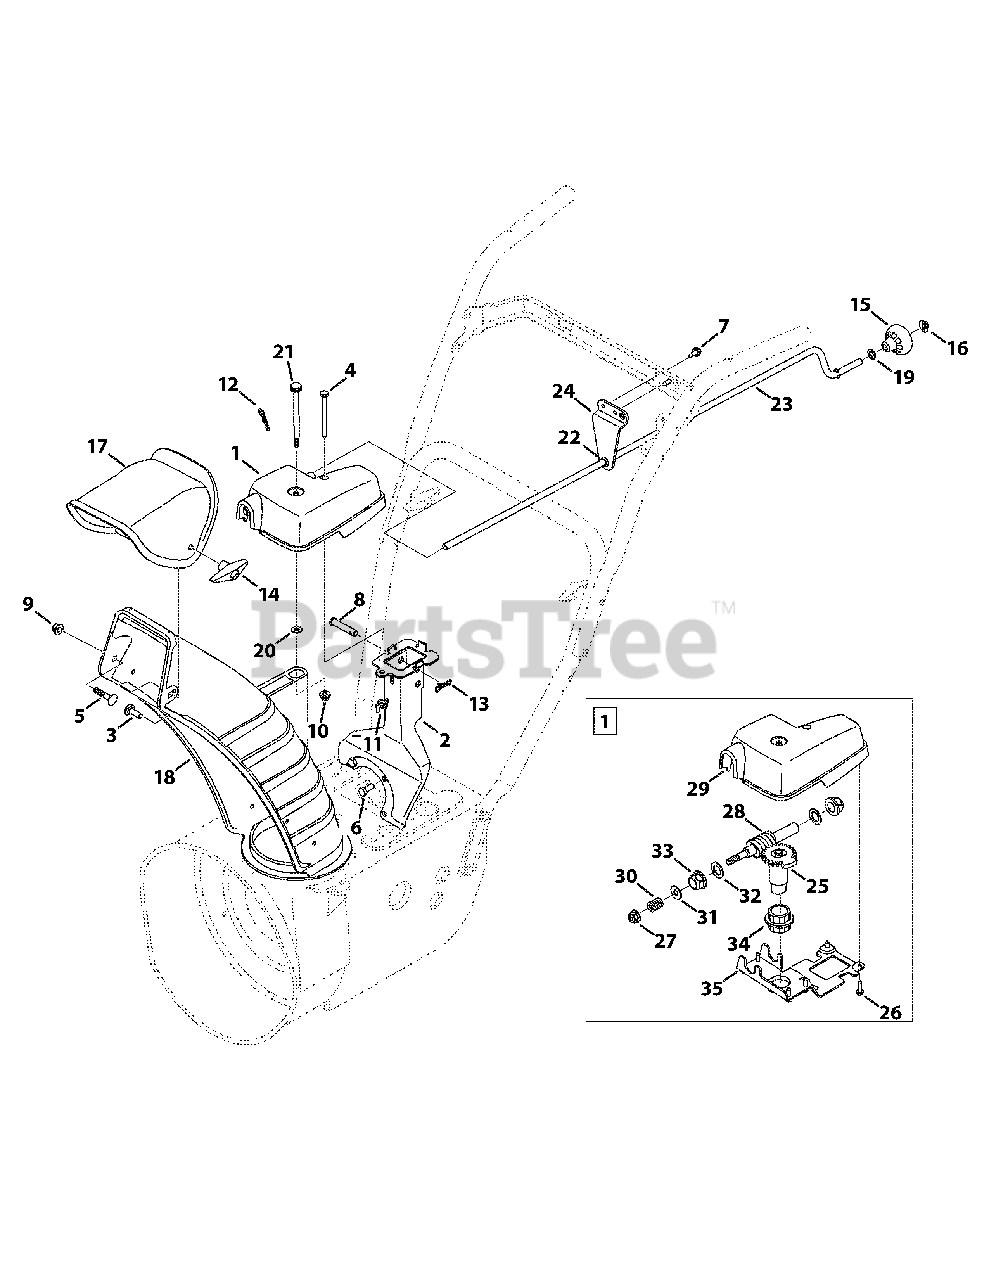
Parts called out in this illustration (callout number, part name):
1	Chute Rotation Gear Box
2	Chute Support Bracket
3	Carriage Bolt, 5.16-18 x 1.00
4	Hex Screw, 1.4-20 x 3.00
5	Carriage Bolt, 5.16-18 x .750
6	Hex Lock Screw, 5.16-24 x .750
7	Hex Washer Screw, 1.4-20 x .625
8	Clevis Pin, 3.8-1.87
9	Flange Lock Nut, 5.16-18
10	Flange Lock Nut, 1.4-20
11	Wing Nut, 1.4-20
12	Cotter Pin, .08 x 1.42
13	Bow-tie Cotter Pin
14	Wing Knob, 5.16-18
15	Shift Knob, .390
16	Push Cap, 3.8
17	Upper Chute
18	Lower Chute, 5.0
19	Flat Washer, .375 x .738 x .063
20	Flat Washer, .25 x .630 x .0515
21	Shoulder Screw, .312 x 3.5 x 1/4-20
22	Plastic Bushing, .380 ID
23	Chute Crank
24	Support Rod Bracket
25	Gear Assembly
26	Screw, 12-16 x .75
27	Flange Lock Nut, 3/8-16
28	Worm Shaft
29	Gear Cover
30	Compression Spring, .39 x .60 x .88
31	Flat Washer, .385 x .87 x .06
32	Flawt Washer, .625 x 1.0 x .067
33	Hex Bearing
34	Flange Bearing
35	Gear Bracket
